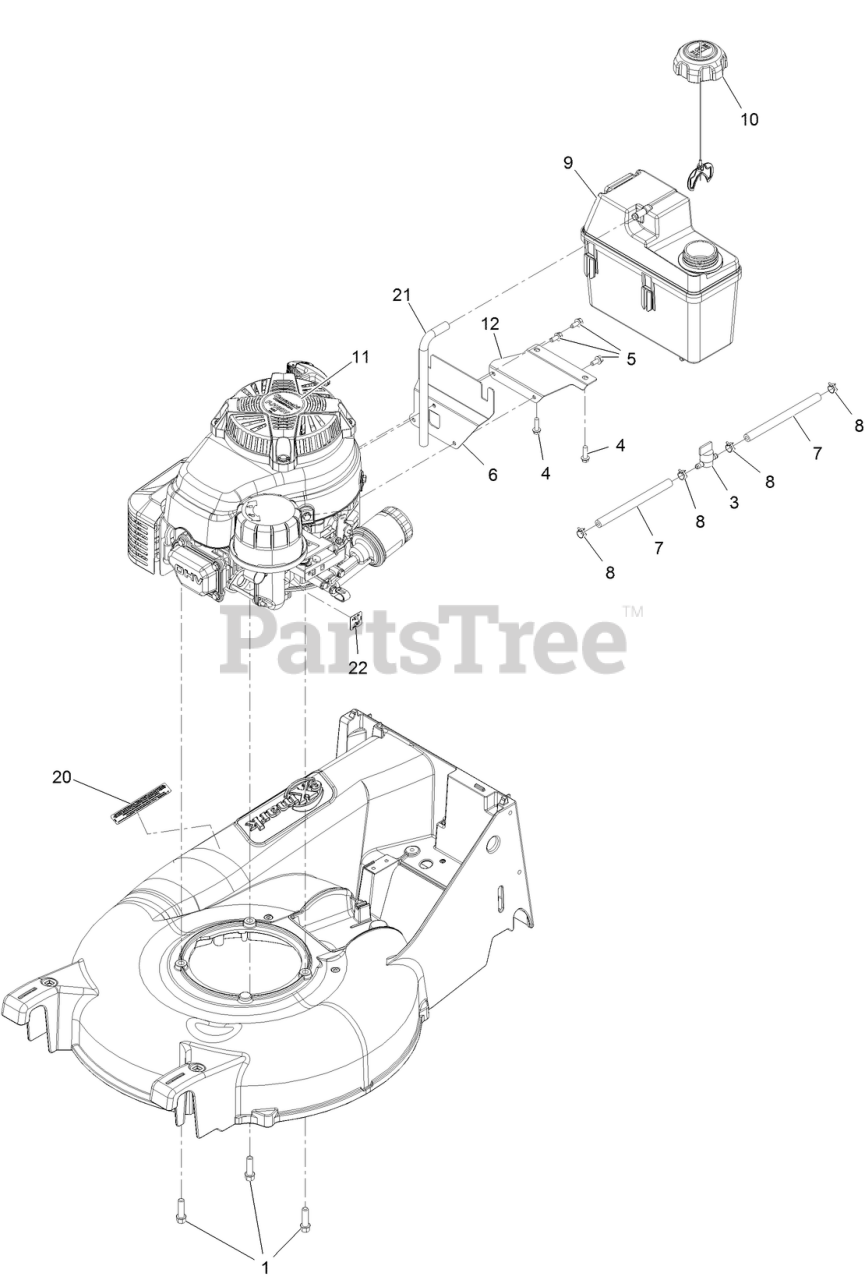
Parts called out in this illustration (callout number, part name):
1	SCREW-TAPTITE
3	VALVE-FUEL
4	SCREW-HWH
5	SCREW-HWH
6	BRACKET-TANK, MOUNTING
7	HOSE-FUEL
8	CLAMP-HOSE
9	TANK-FUEL
10	CAP-FUEL
12	BRACKET-TANK, SUPPORT
20	DECAL-ARRESTOR, SPARK
21	HOSE-VENT, CANISTER
22	DECAL-PRIMER
